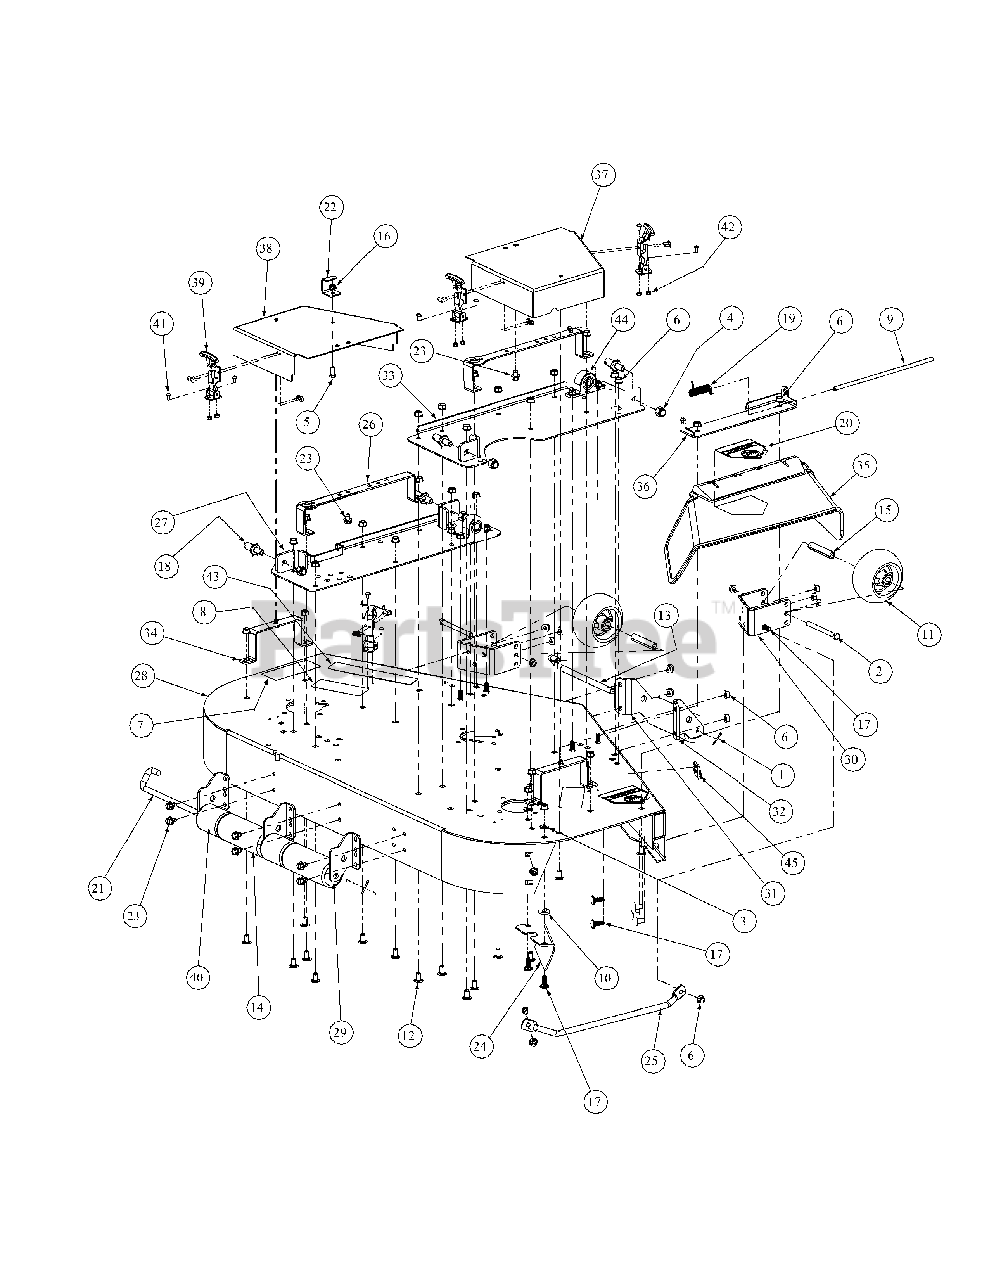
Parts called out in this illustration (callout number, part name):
1	Cotter Pin, .125 Dia. x 1.0
2	Hex Cap Screw, 3/8-16, 3.75
3	Flat Washer, 3/8
4	Lock Nut, Nylon Insert, 1/2-13
5	Hex Cap Screw, 5/16-18 x 3/4
6	Flange Lock Hex Nut, 3/8-16
7	Decal Rotating Blade
8	Decal Warning Shield Missing
9	Chute Deflector Rod
10	Idler Washer
11	Complete Wheel, 5.00 Dia
12	Carriage Bolt, 3/8-16 x .75 Lg
13	Roller Pin, 1/2 Dia x 7.31 Lg
14	Front Roller
15	Wheel Spacer
16	Hex Flange Lock Nut, 5/16-18
17	Carriage Bolt, 3/8-16 x 1
18	Pin, 5/8 Dia. x 1.2 Lg.
19	Torsion Spring, 0.4 ID x 2.16 LG
20	Decal, Danger Hands and Feet
21	Roller Rod
22	Bracket Stop Tension Rod
23	Hex Index Washer Screw, 3/8-16, .05
24	Fabricated Deck, Chute Bracket
25	Fabricated Deck Finger Guard
26	Fabricated Belt Support Cover
27	Left Hand Deck Bracket Assembly
28	48 Fabricated Deck Assembly
29	Fabricted Deck Roller Mount Bracket
30	Front Anti-Scalp Wheel Mount Bracket
33	Right Hand Deck Bracket Assembly
34	Outer Belt Cover Support Assembly
35	Deflector Chute
36	Deflector Chute Bracket
37	Right Hand Belt Cover
38	Left Hand Belt Cover
39	Latch Drawing, T-Handle
41	Phillip Head Screw, 10-32
42	Lock Nut, Nylon Insert, 10-32
44	Pillow Block
45	Decal, 48"
